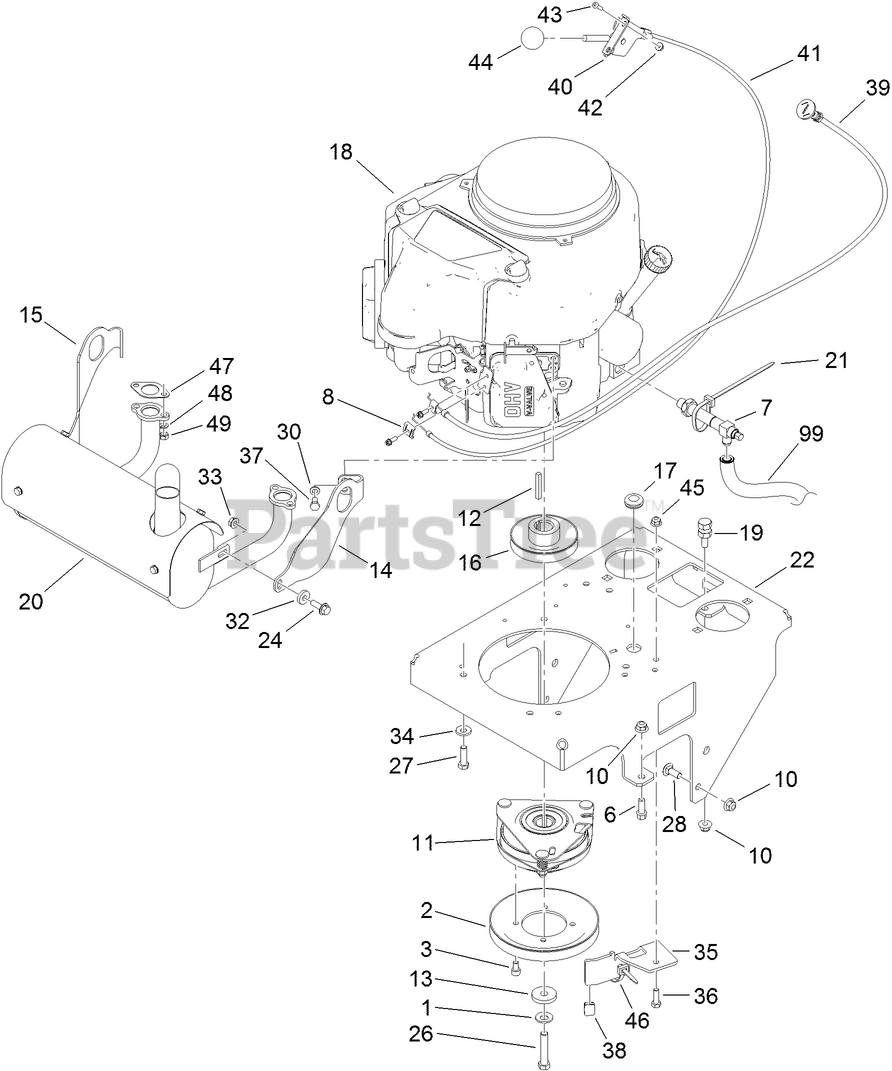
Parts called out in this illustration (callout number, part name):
1	WASHER-SPRING
2	PULLEY
3	SCREW-HSH
6	SCREW-HWH
7	VALVE-DRAIN, OIL
8	CLAMP-CABLE
10	NUT-HF, NI
11	CLUTCH/BRAKE ASM
12	KEY-SQUARE
13	WASHER
14	BRACKET-MUFFLER MOUNT, LH
15	BRACKET-MUFFLER MOUNT, RH
16	PULLEY
17	GROMMET
19	ANCHOR-SPRING, SHORT
20	MUFFLER
21	TIE-CABLE
22	BASE-ENGINE
24	SCREW-HHF
26	SCREW-HH
27	SCREW-HH
28	BOLT-CARR
30	WASHER-LOCK
32	SPACER
33	NUT-HF
34	WASHER-BELLEVILLE
35	BRACKET-STOP, PTO
36	SCREW-HH
37	SCREW-HH
38	BUMPER
39	Control-Choke, Push / Pull
40	LEVER-CONTROL
41	CABLE-CONTROL
42	NUT-LOCK, FLANGE
43	BOLT-CARR
44	KNOB-BALL
45	NUT-HF, NI
46	TIE-CABLE
47	GASKET-EXHAUST
48	WASHER-LOCK
99	HOSE-DRAIN, OIL
